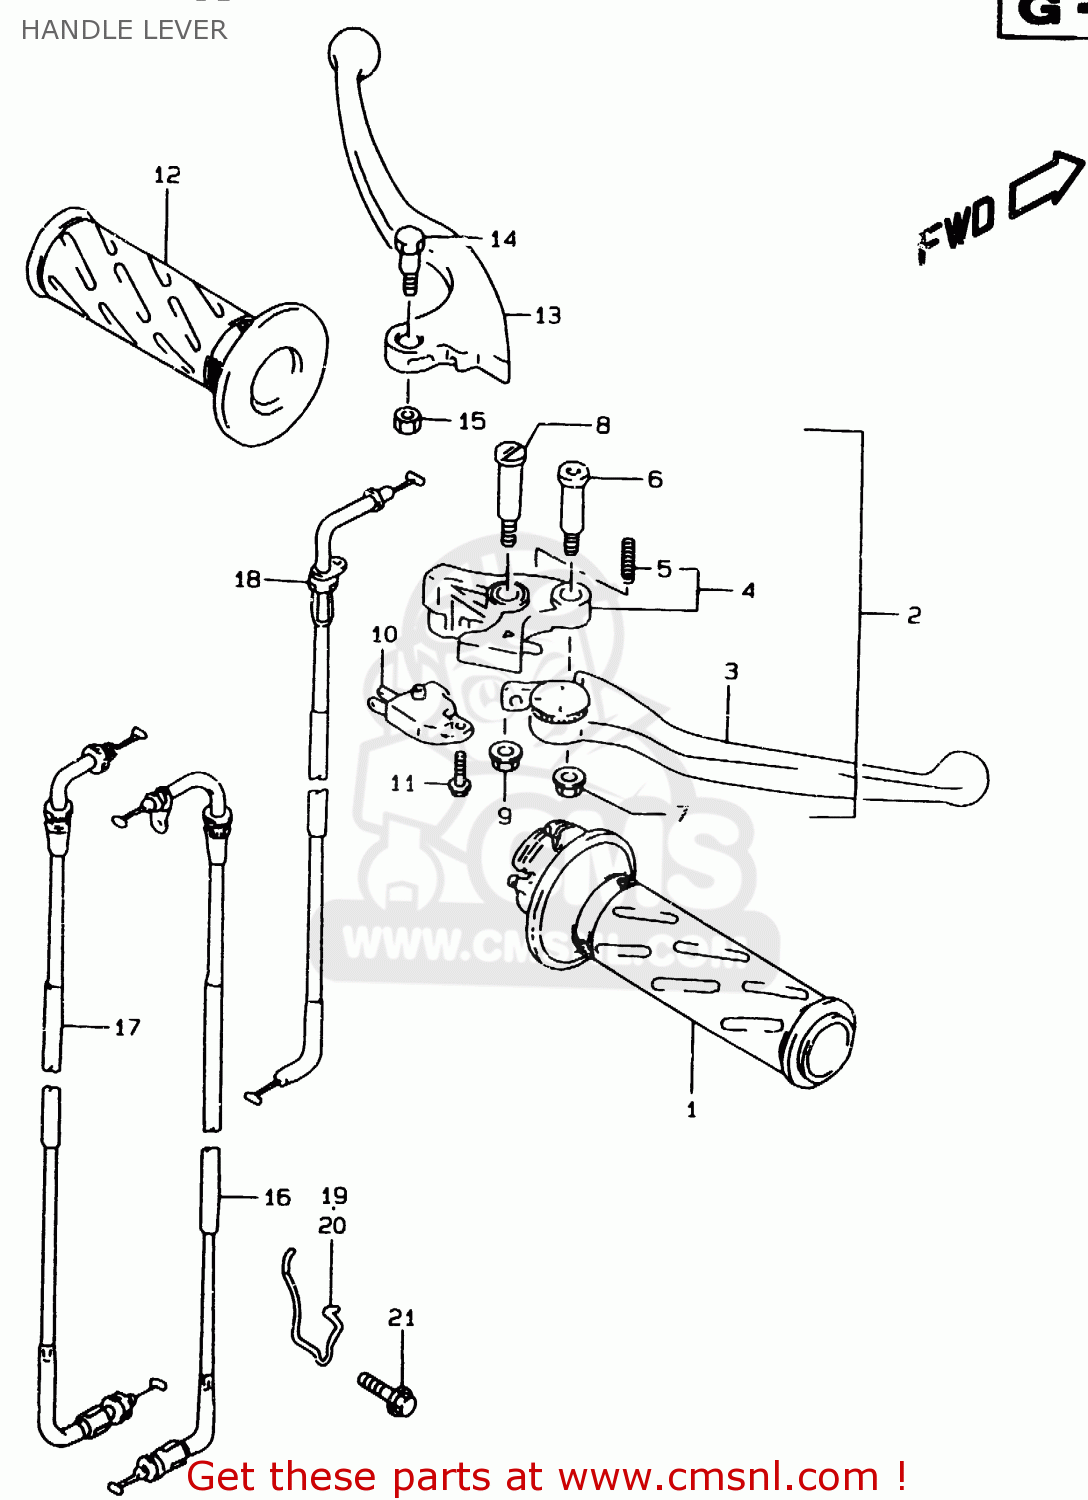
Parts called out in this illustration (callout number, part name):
1	GRIP,THROTTLE
2	LEVER ASSY,BRAKE
3	LEVER,ADJUST
4	KNOCKER
5	SPRING
6	BOLT,LEVER
7	NUT
8	BOLT,LEVER PIVOT
9	NUT
10	SWITCH ASSEMBLY,STOP
11	SCREW
12	GRIP,LEFT
13	LEVER,CLUTCH (SILVER)
14	BOLT,LEVER
15	NUT
16	CABLE ASSY,THROTTLE NO.1
17	CABLE ASSY,THROTTLE NO.2
18	CABLE,STARTER
19	GUIDE,CABLE NO.1
20	GUIDE,CABLE NO.2
21	BOLT
